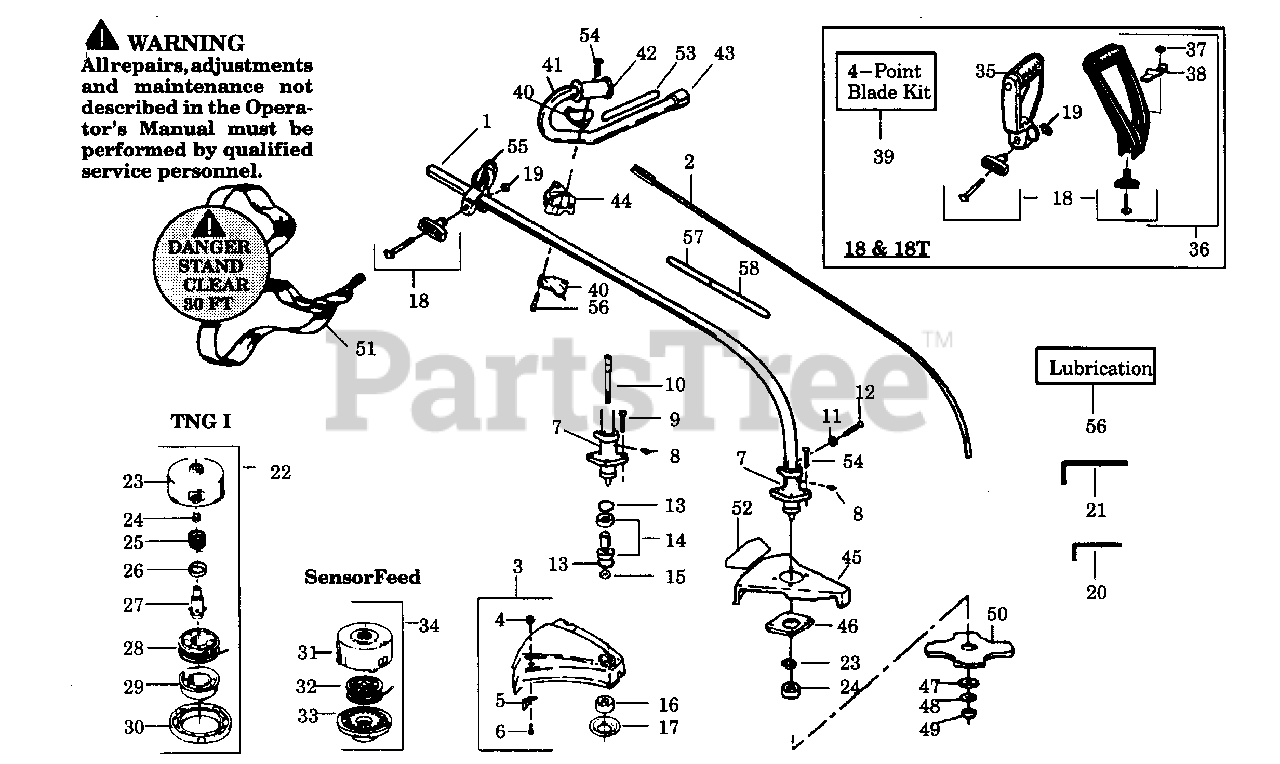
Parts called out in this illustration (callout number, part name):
1	MODELS GTI 18,GTI 18K,GTI 18T,GTI 18KT-Type 2
1	MODEL GTI 18KT Type 3
2	Drive Shaft
3	Shield Kit Ass'y.
4	Locknut)
5	Line Limiter
7	Bearing Hsg.
9	Screw-Plastic Shield
10	Arbor Shaft
13	Retainer
14	Bearings & Spacer Kit
16	Dust Cup
17	Grass Washer
18	"T" Handle Kit
20	Hex Wrench (5/32")
21	Hex Wrench (3/16")
22	Cutting Head Ass'y.
23	Hub
24	Line Saver
26	Spring Cap
27	Drive Gear
28	Spool w/Line
29	Release Button
31	Hub Ass'y.
32	Spool w/Line
34	Cutting Head Ass'y.
35	Handle MODELS GTI 18,GTI 18T
36	Assist Handle Kit
37	Nut MODELS GTI 18,GTI 18T
38	Clamp MODELS GTI 18,GTI 18T
39	4 Point Blade Kit MODELS GTI 18,GTI 18T
40	Handlebar Bracket MODELS GTI 18K, GTI 18KT
41	Handlebar MODELS GTI 18K, GTI 18KT
42	Handlebar Grip MODELS GTI 18K, GTI 18KT
43	Handlebar Cap MODELS GTI 18K, GTI 18KT
44	Handlebar Clamp MODELS GTI 18K, GTI 18KT
45	Shield w/Decal MODELS GTI 18K, GTI 18KT
46	Shield Retention Plate MODELS GTI 18K, GTI 18K
47	Washer-Blade MODELS GTI 18K, GTI 18KT
48	Washer-Belleville MODELS GTI 18K, GTI 18KT
49	Nut-Blade MODELS GTI 18K, GTI 18KT
50	4-Point Blade MODELS GTI 18K, GTI 18KT
51	Shoulder Strap MODELS GTI 18K, GTI 18KT
52	Blade Direction Decal MODELS GTI 18K, GTI 18KT (Not a serviceable part)
53	Handlebar Decal MODELS GTI 18K, GTI 18KT
54	Screw-Metal Shield/& Handlebar MODELS GTI 18K, GTI 18KT
55	Clamp-Harness MODELS GTI 18K, GTI 18KT
56	Shaft Lubrication
57	Shaft Warning-Upper
58	MODELS GTI 18KT Type 2,GTI 18,GTI 18K,GTI 18T
58	MODEL GTI 18KT Type 3
